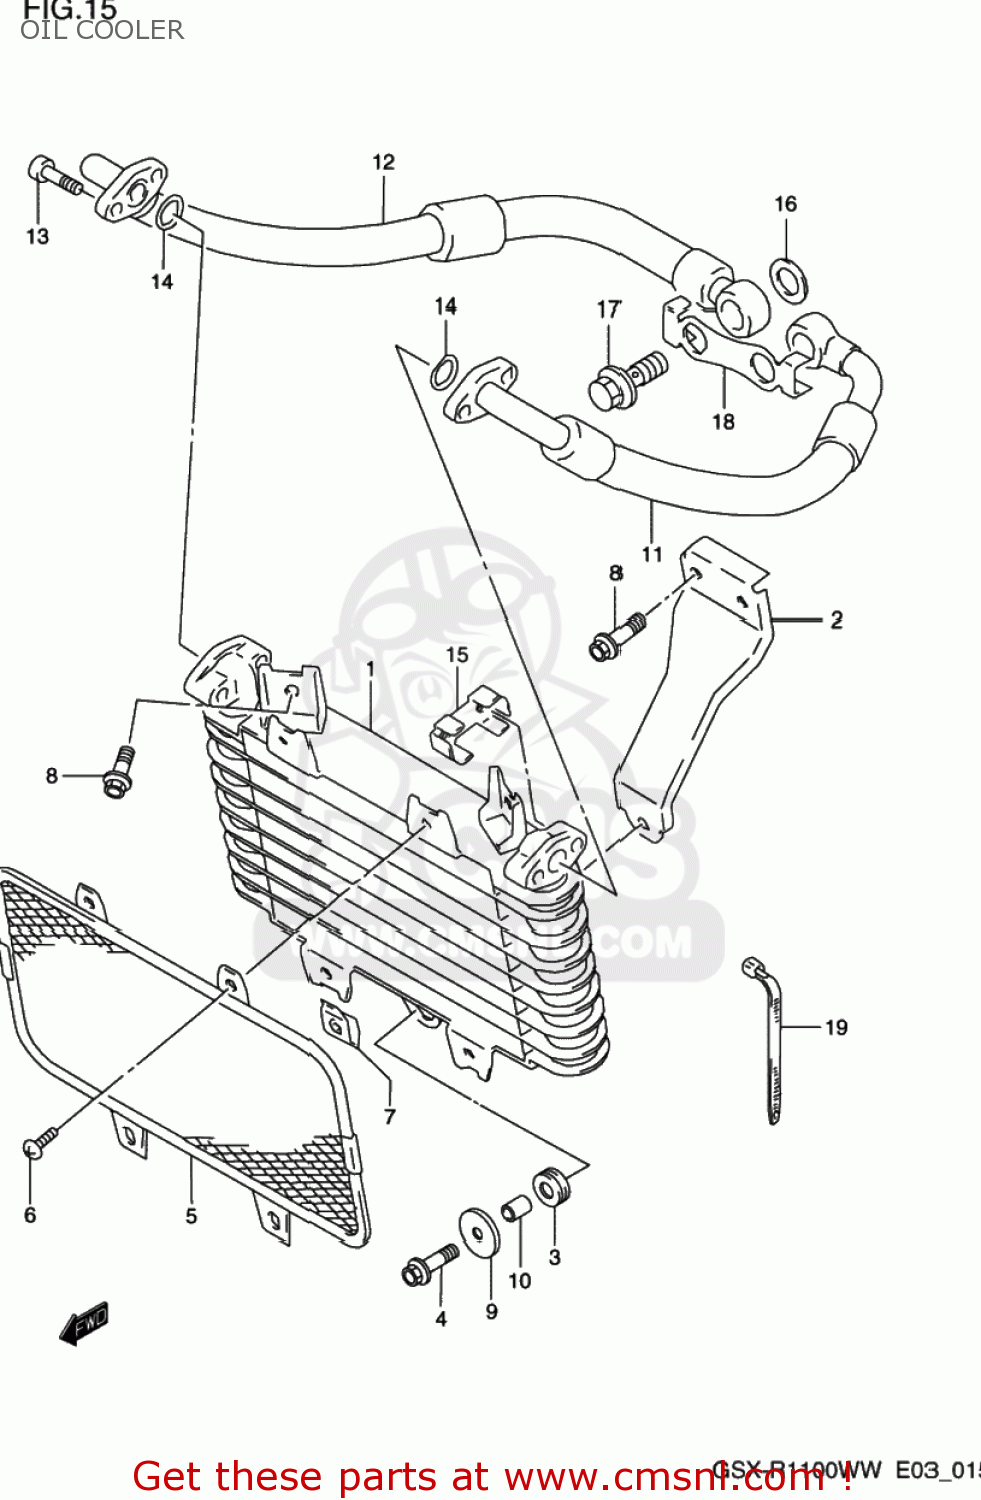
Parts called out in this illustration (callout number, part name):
1	COOLER ASSY,OIL
2	BRACKET COMP,OIL COOLER
3	CUSHION
4	BOLT
5	GUARD,OIL COOLER
6	SCREW
7	NUT
8	BOLT
9	WASHER
10	SPACER(6.5X10X10)
11	HOSE,OIL COOLER INLET
12	HOSE,OIL COOLER OUTLET
13	BOLT
14	O RING(D:2.4,ID:12.3)
15	NUT,OIL COOLER HOSE
16	GASKET(16X22X2) (NAS)
17	BOLT UNION
18	GASKET,OIL COOLER HOSE UNION
19	CLAMP
